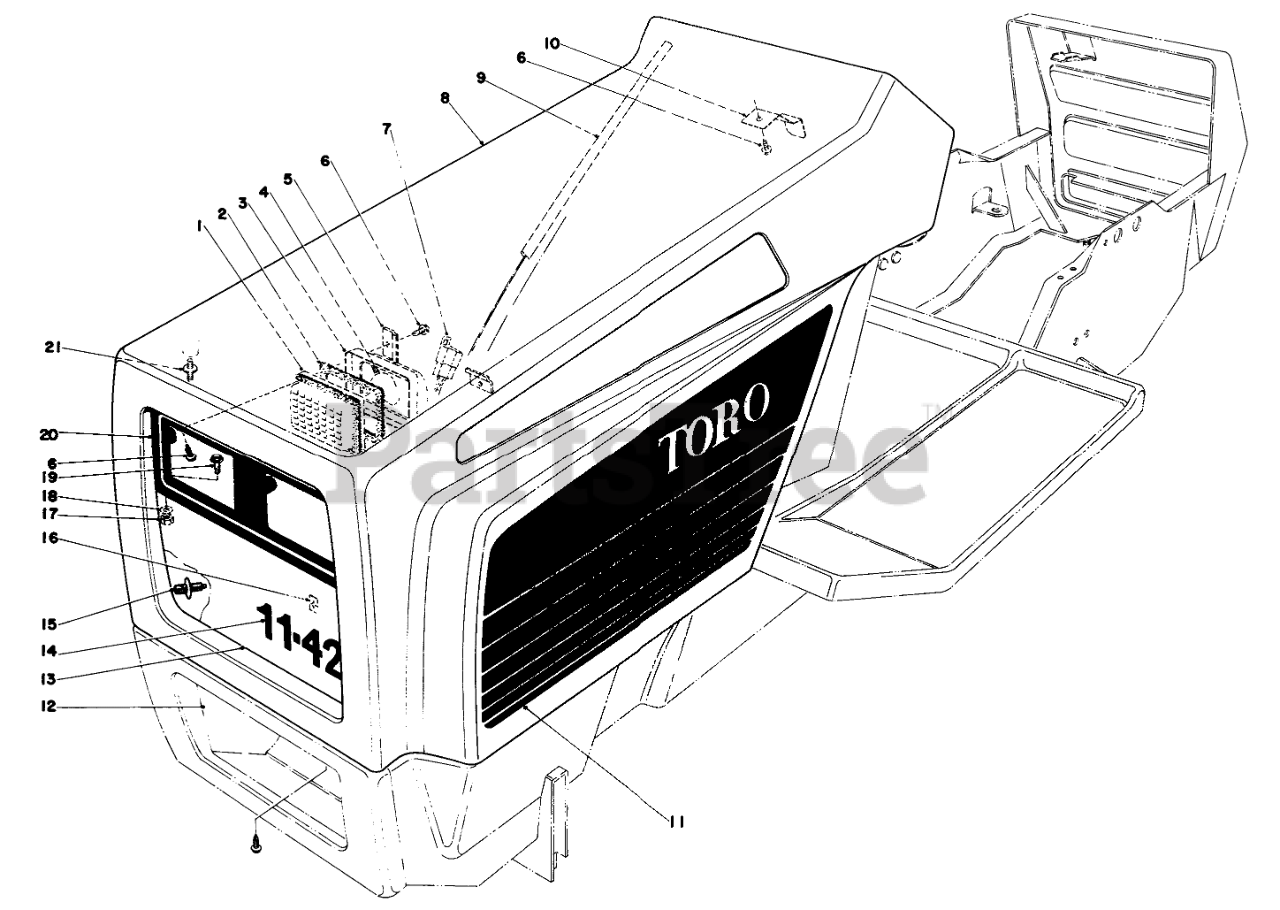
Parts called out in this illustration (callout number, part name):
1	Lens
2	Gasket Lens
3	Reflector
5	HEADLIGHT CLAMP
6	SCREW-HWHTF
7	CONNECTOR BODY
8	Hood (Incl. Ref. #15 & 21)
9	RUBBER EXT SEAL
10	SPRING LATCH
11	Decal Hood LH.
12	LOWER GRILLE
13	HEADLIGHT GRILLE
14	GRILLE NAMEPLATE
15	HINGE BRKT STUD
17	NUT-LOCK, SIDE
18	WASHER-FLAT
19	SCREW-SHWH
20	HEADLIGHT PANEL B
21	Stud Hood Duct
